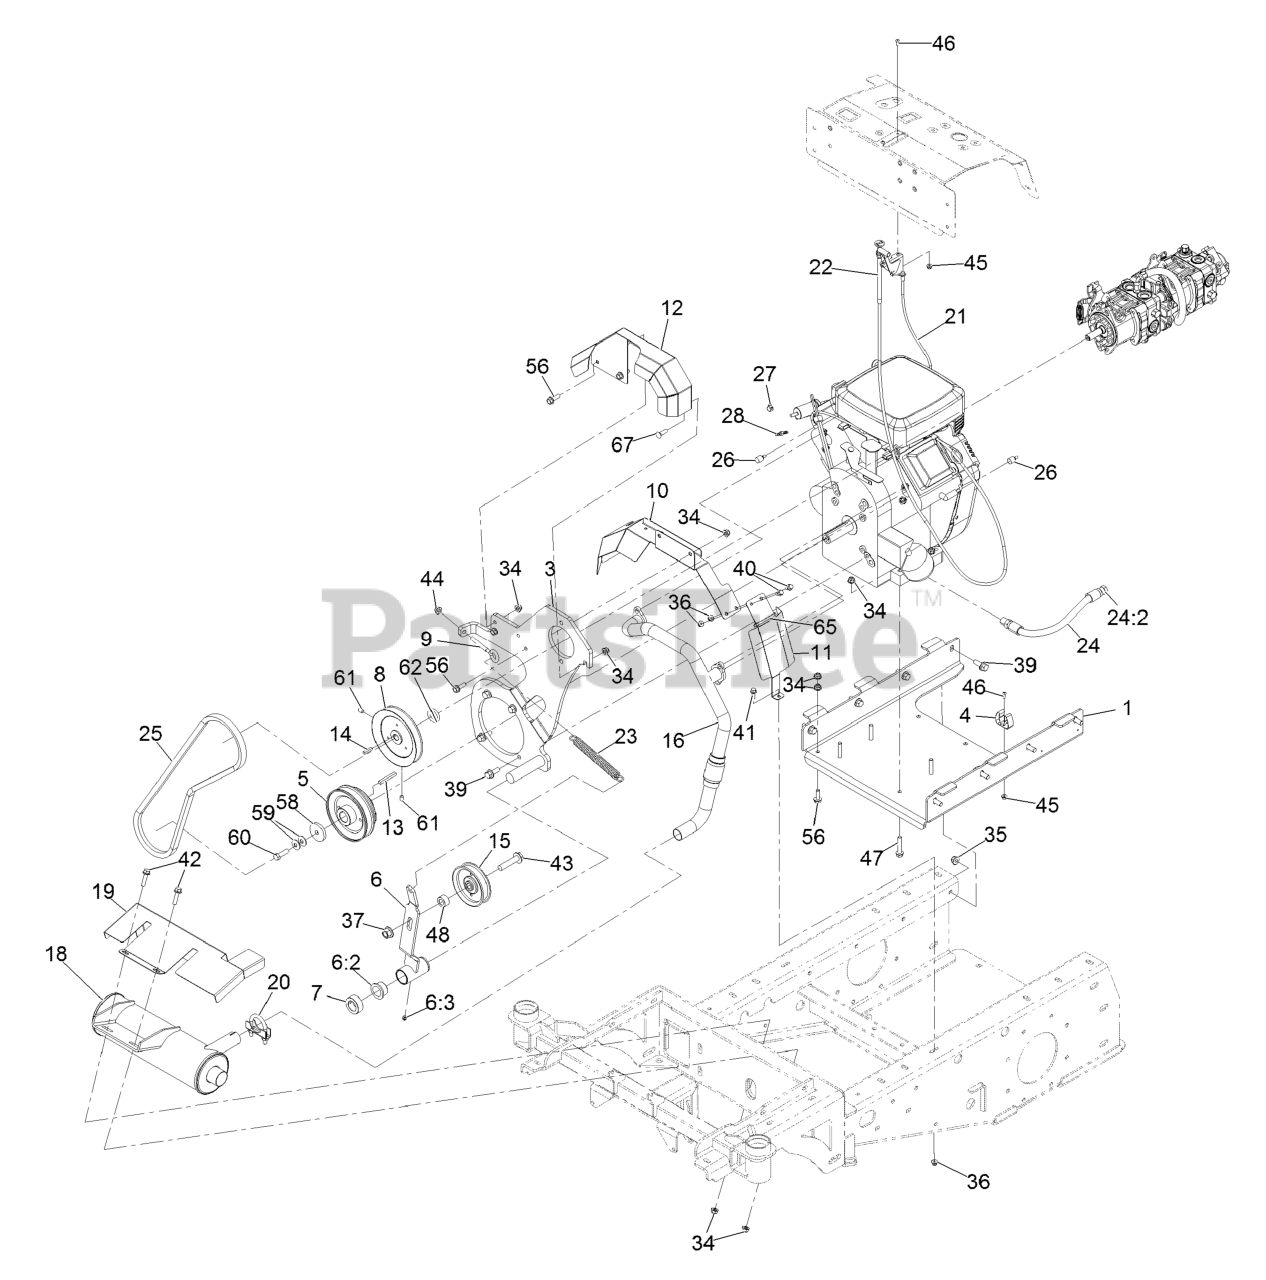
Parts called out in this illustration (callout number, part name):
1	Tray-Engine
3	Bracket-Engine, Pump [black]
4	Holder-Tool, Clip
5	Pulley-Double
6	Arm-Tension, ASM
6:2	BUSHING-FLANGE
6:3	FITTING-GREASE, ZERK
8	PULLEY-DRIVE, PUMP
9	Bolt-Eye
10	Guard, Lower Muffler
11	Guard, Lower Muffler
12	GUARD-PULLEY
15	PULLEY-IDLER, FLAT
16	MANIFOLD-EXHAUST
18	MUFFLER
19	SHIELD-HEAT, MUFFLER
20	Clamp-Muffler
21	CABLE-THROTTLE
22	CABLE-CHOKE
23	SPRING-EXTENSION
24	ASM, Oil Drain Hose W/Plug
26	Tube-Heat Shrink, 1/2
27	CLAMP-HOSE
28	Fitting-STR
34	Nut-Hex Flange
35	Nut-Hex Flange
36	Nut-Hex Flange
37	Nut-Lock 1/2-13
39	SCREW-HHF
40	SCREW-HHF
41	Screw-HHF
42	SCREW-HHF
43	Screw-HHF
44	NUT-HF, NI
45	Nut-Hex Flange
46	Screw-HSBH
47	Screw-HHF
56	SCREW-HHF
58	WASHER-PLAIN
59	WASHER-BELLEVILLE
60	Screw-HH
61	Setscrew-HSH
65	TIE-CABLE
67	Bolt,Carriage,5/16-18X1,ST/ST 18-8
